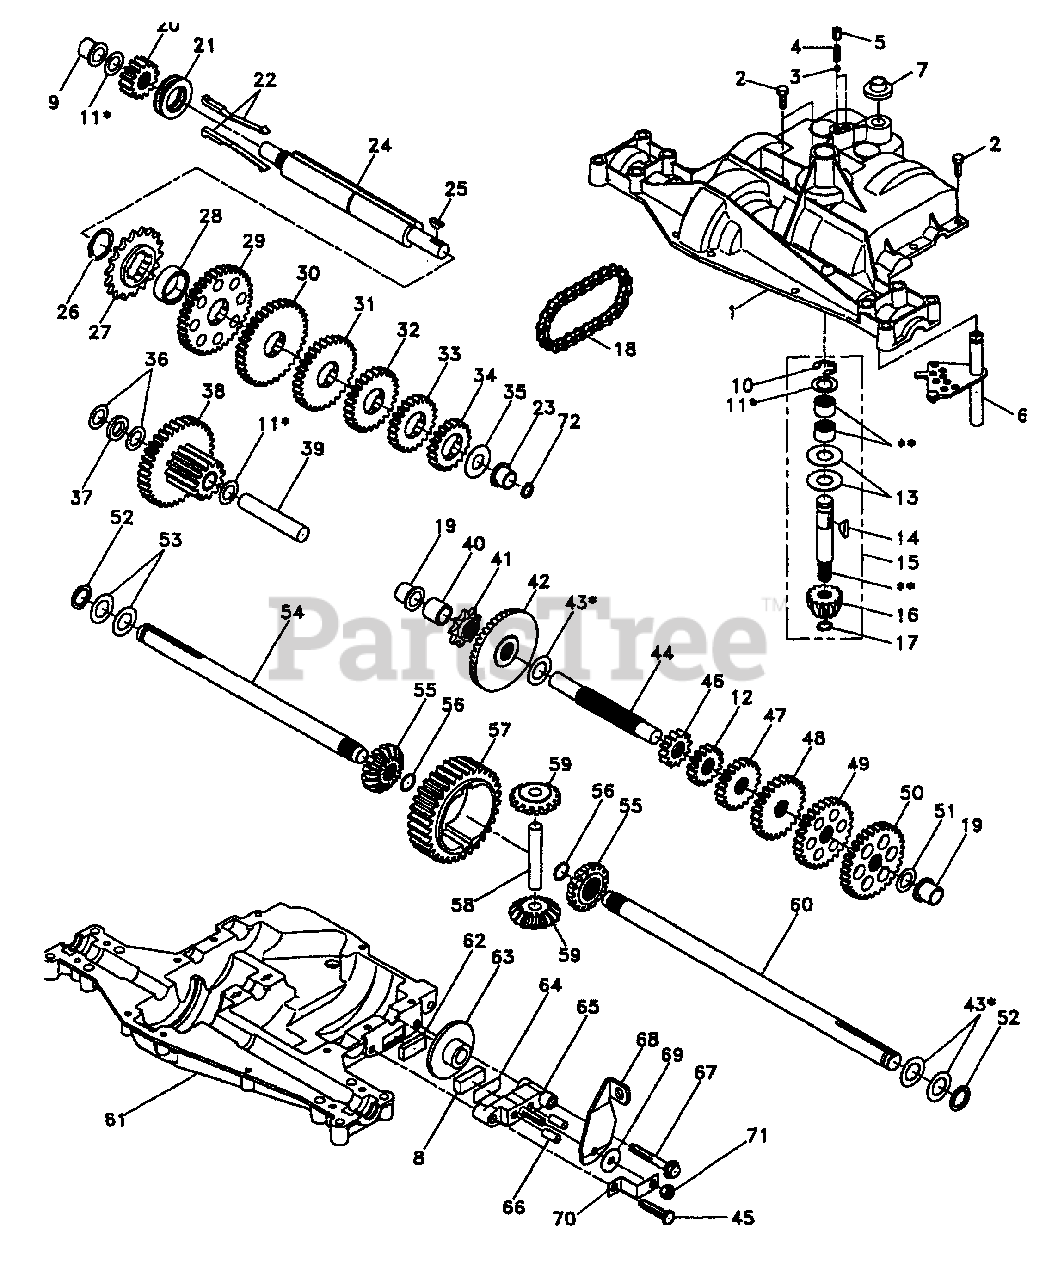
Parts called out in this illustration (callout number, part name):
1	Housing, Upper
2	Screw, Tapping, Large 1/4-20 x .734
3	Ball, Detent
4	Spring, Detent
5	Screw, Set
6	Kit, Shifter Assembly
7	Boot, Shifter
8	Puck, Friction
9	Bearing, Flange
10	Ring, Retaining
11	Assembly, Kit, Shim, .625 Shaft
12	Gear, Spur, 15 Teeth
13	Washer, Plain .632 x 1.38 x .046
14	Key, Woodruff, #9
15	Assembly, Kit, Input Shaft
16	Pinion, Bevel, 14 Teeth
17	Ring, Retaining
18	Chain, 24 Pitches
19	Bearing, Flange
20	Gear, Spur, 14 Teeth
21	Collar, Clutch
22	Assembly, Kit, Clutch Keys
23	Bearing, Flange
24	Shaft, Intermediate
25	Key, Woodruff, #61
26	Ring, Retaining
27	Sprocket, 18 Teeth
28	Spacer
29	Gear, Spur, 37 Teeth
30	Gear, Spur, 35 Teeth
31	Gear, Spur, 30 Teeth
32	Gear, Spur, 25 Teeth
33	Gear, Spur, 22 Teeth
34	Gear, Spur, 19 Teeth
35	Washer, Plain .640 x 1.37 x .061
36	Washer, Plain .632 x 1.00 x .026
37	Spacer .630 x 1.00 x .169
38	Assembly, Gear, Combination, 12 Teeth and 35 Teeth
39	Shaft, Idler
40	Spacer .633 x .87 x .755
41	Sprocket, 9 Teeth
42	Gear, Bevel, 42 Teeth
43	Assembly, Kit, Shim, .750 Shaft
44	Shaft, Drive
45	Screw, Tapping, Large 5/16-18 x 1.44
46	Gear, Spur, 12 Teeth
47	Gear, Spur, 20 Teeth
48	Gear, Spur, 25 Teeth
49	Gear, Spur, 28 Teeth
50	Gear, Spur, 31 Teeth
51	Washer, Plain .632 x 1.00 x .060
52	Washer, Neoprene
53	Washer, Plain .758 x 1.25 x .031
54	Axle, L.H.
55	Gear, Miter, 15 Teeth
56	Ring, Retaining
57	Gear, Spur, 32 Teeth
58	Shaft, Cross
59	Gear, Miter, 15 Teeth
60	Axle, R.H.
61	Housing, Lower
62	Puck, Friction
63	Disc, Brake
65	Jaw, Brake
66	Pin, Dowel
67	Screw, Tapping 5/16-18 x 2.25
68	Lever, Actuating
69	Washer, Plain .321 x 1.00 x .055
70	Bracket, Anti-Rotation
71	Locknut 5/16-24
72	Seal, Oil
